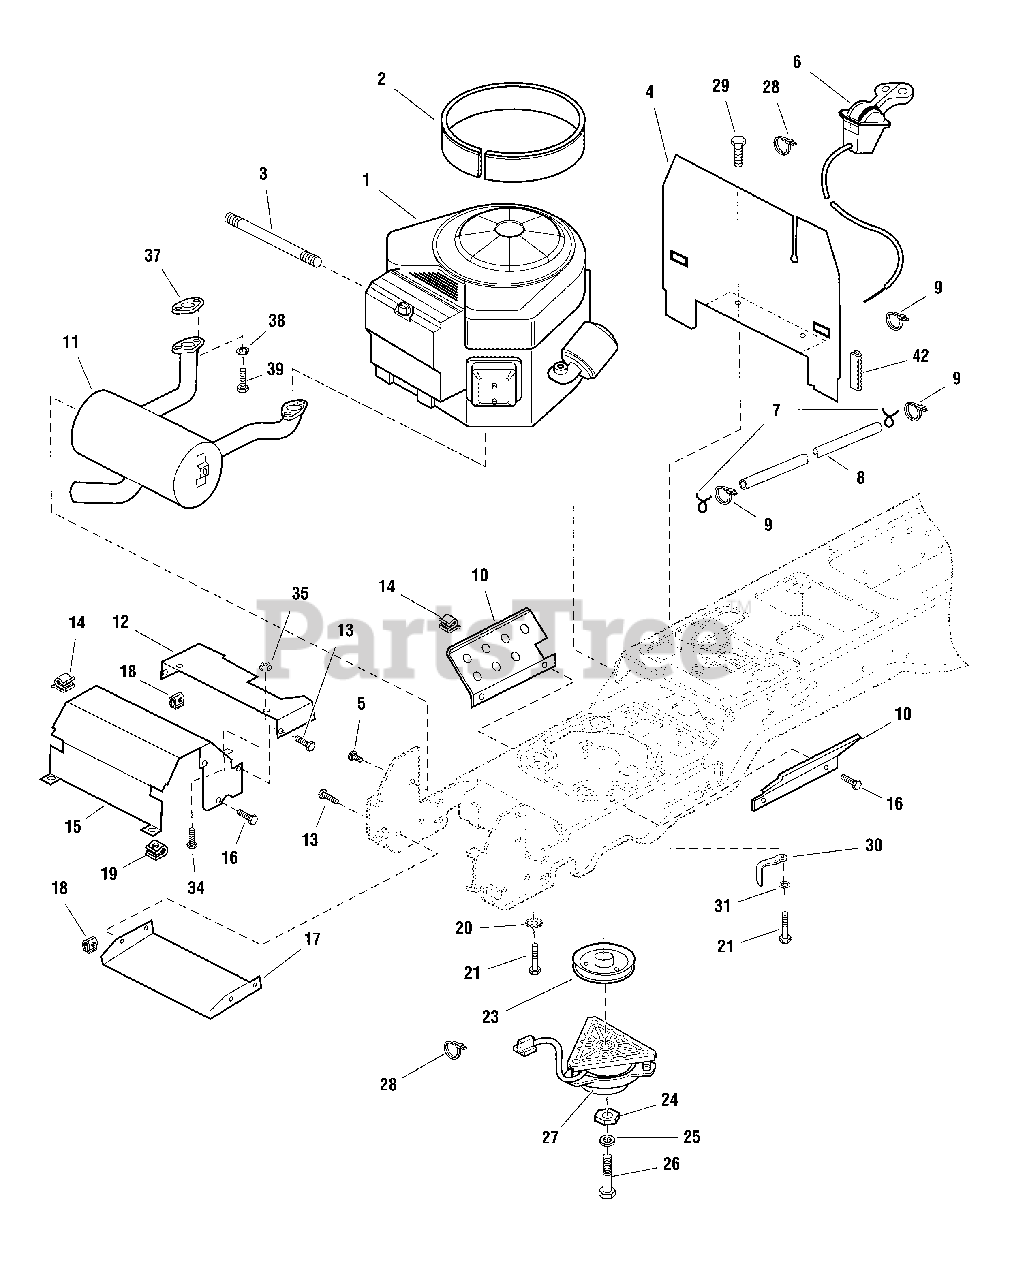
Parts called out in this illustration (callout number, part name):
1	* ENGINE, 22 HP Briggs & Stratton Pro Series Twin, Model 40H777-2136-G5
2	EDGING, Airduct
3	HOSE, Oil Drain
4	HEAT SHIELD
5	CAPSCREW, Hex Head, Taptite, 5/16-18 x 1/2
6	THROTTLE CONTROL
7	CLAMP, Hose
8	HOSE, Fuel
9	TIE, Self Locking, 7-5/16 Long
10	SHIELD, Side, Heat
11	MUFFLER ASSEMBLY
12	DUCT, Muffler Extension
13	CAPSCREW, Hex, Whiz Lock, 1/4-20 x 5/8
14	CLIP, Wire
15	DUCT, Muffler Top
16	CAPSCREW, Hex Head Taptite, 1/4-20 x 3/8
17	SHIELD, Muffler Bottom
18	NUT, Speed, 1/4-20
19	NUT, Speed, Lug Type, 5/16-18
20	WASHER, Locking, External Teeth, 3/8
21	CAPSCREW, Hex Head, Taptite, 3/8-16 x 1-1/2
23	PULLEY & HUB ASSEMBLY, Engine
24	WASHER, Hex, 7/16 x 1-1/2
25	WASHER, Locking, 7/16
26	CAPSCREW, Hex Head 7/16-20 x 3-1/2
27	CLUTCH, Electric
28	TIE, Self Locking
29	CAPSCREW, Hex Head Taptite, 1/4-20 x 1/2
30	GUIDE, Belt Retainer, Clutch
31	WASHER, Flat, 3/8
34	CAPSCREW, Allen Head 1/4-20
35	NUT, 1/4-20 Hex Serrated Flange
37	GASKET, Exhaust
38	LOCKWASHER, 5/16
39	CAPSCREW, Socket Head, 5/16-18 x 7/8, G8
